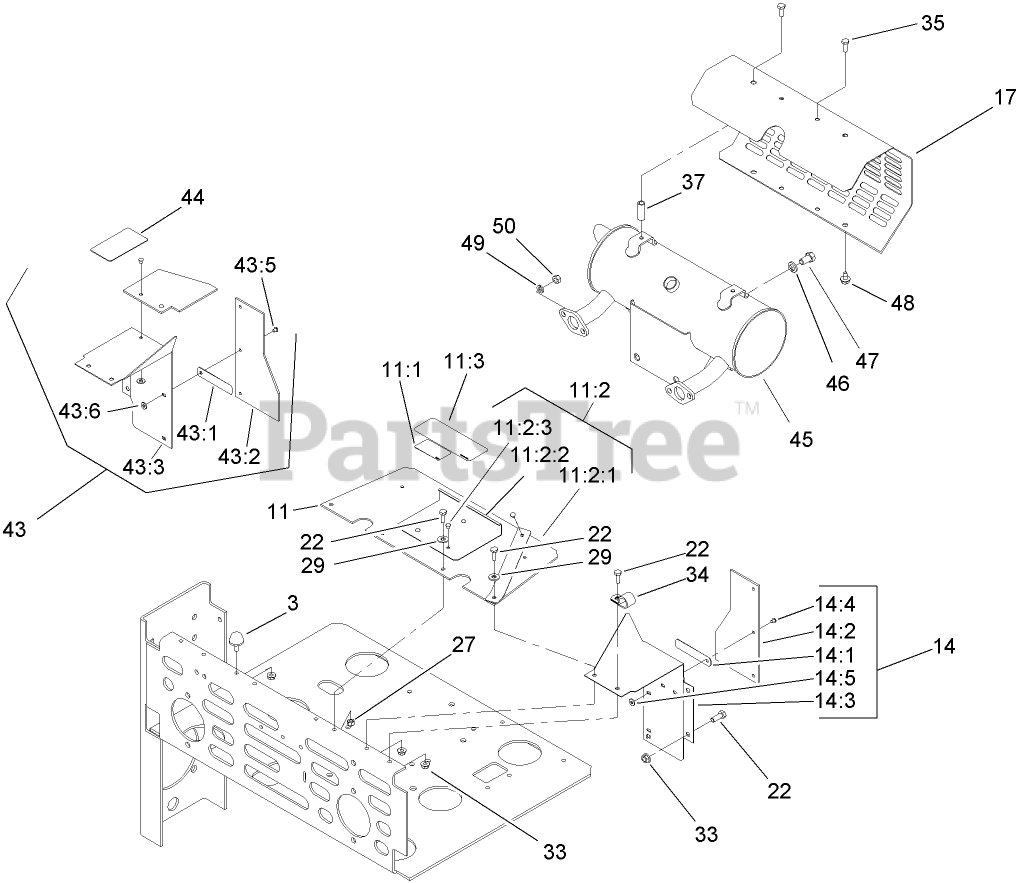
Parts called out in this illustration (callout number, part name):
3	BUMPER
11	SHIELD ASM
11:1	DECAL-IMPORTANT
11:2	Drive Cover ASM
11:2:1	SHIELD-ENGINE
11:2:2	PLATE-COVER, DRIVE
11:2:3	RIVET-POP
11:3	DECAL-DEVICES, ROTATING
14	LH Extended Shield ASM
14:1	CLIP-BAFFLE, REAR
14:2	SHIELD
14:3	BAFFLE-ENGINE SHIELD, LH
14:4	RIVET-POP
14:5	WASHER-FLAT
17	GUARD-MUFFLER
22	SCREW-HH
27	NUT-LOCK, NI
29	WASHER-FLAT
33	NUT-HF
34	CLIP-LOOM
35	SCREW-HWH
37	SPACER
43	RH Extended Shield ASM
43:1	CLIP-BAFFLE, REAR
43:2	SHIELD
43:3	SHIELD-RH
43:5	RIVET-POP
43:6	WASHER-FLAT
44	DECAL-ROUTING, BELT
45	Muffler
46	WASHER-LOCK
47	SCREW-HH
48	SCREW
49	WASHER-LOCK
50	NUT-HEX
